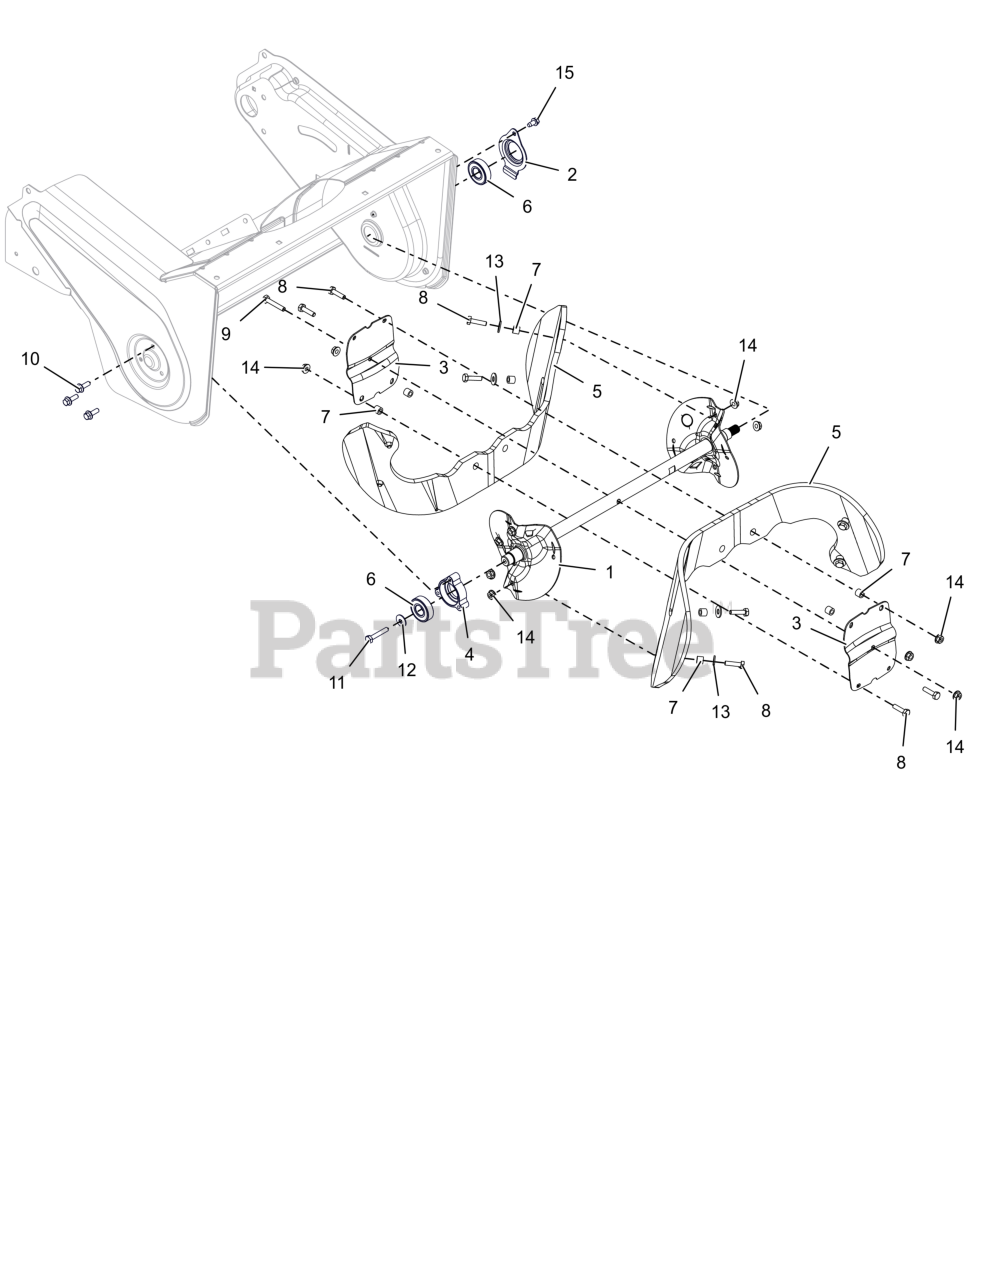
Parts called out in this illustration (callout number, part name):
1	AUGER, WELDMENT
2	CAP, BRG
3	PLATE, CENTER AUGER
4	HOLDER, BEARING - PM
5	FLIGHTING, AUGER
6	BRG-BALL .669X1.575X.47(6203Y)
7	BUSHING,.26 ID X .44 OD X .375
8	BLT,HEX .25-20X1.00 G5 ZCC
9	BLT, HEX .25-20X1.50 G5 ZCC
10	BLT,HEX-FLG .25-20X.75 G5 ZCC
11	BLT, HEX .25-20X1.50 G8 ZCC
12	WSHR,BLVL-.250X.815X.061 ZFS
13	WSHR, FLT .312X.734X.065 ZCC
14	NUT-LK-TOP-FLG .250-20 GF ZCC
15	SCR-TAP .25-20X.50 HWH ZCC
